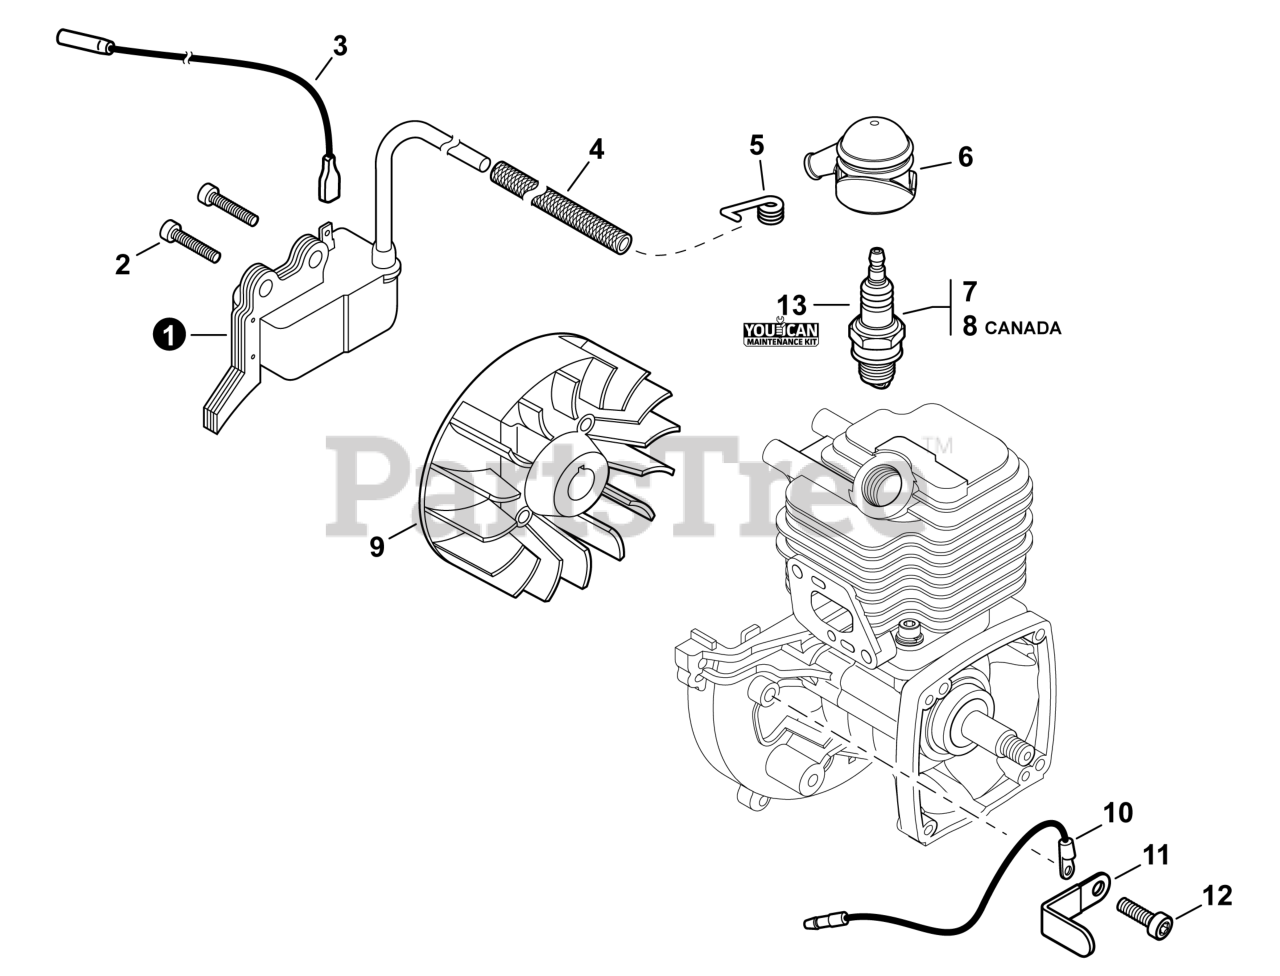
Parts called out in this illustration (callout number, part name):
1	COIL, IGNITION
2	BOLT, TORX 4x20
3	LEAD - IGNITION L= 210
4	TUBE, INSULATOR
5	TERMINAL, SPARK PLUG
6	CAP, SPARK PLUG
7	SPARK PLUG - BPM8Y
8	SPARK PLUG - BPMR8Y
9	FLYWHEEL
10	LEAD - GROUND L= 115
12	BOLT, TORX 5x10
13	TUNE-UP KIT - YOUCANT
